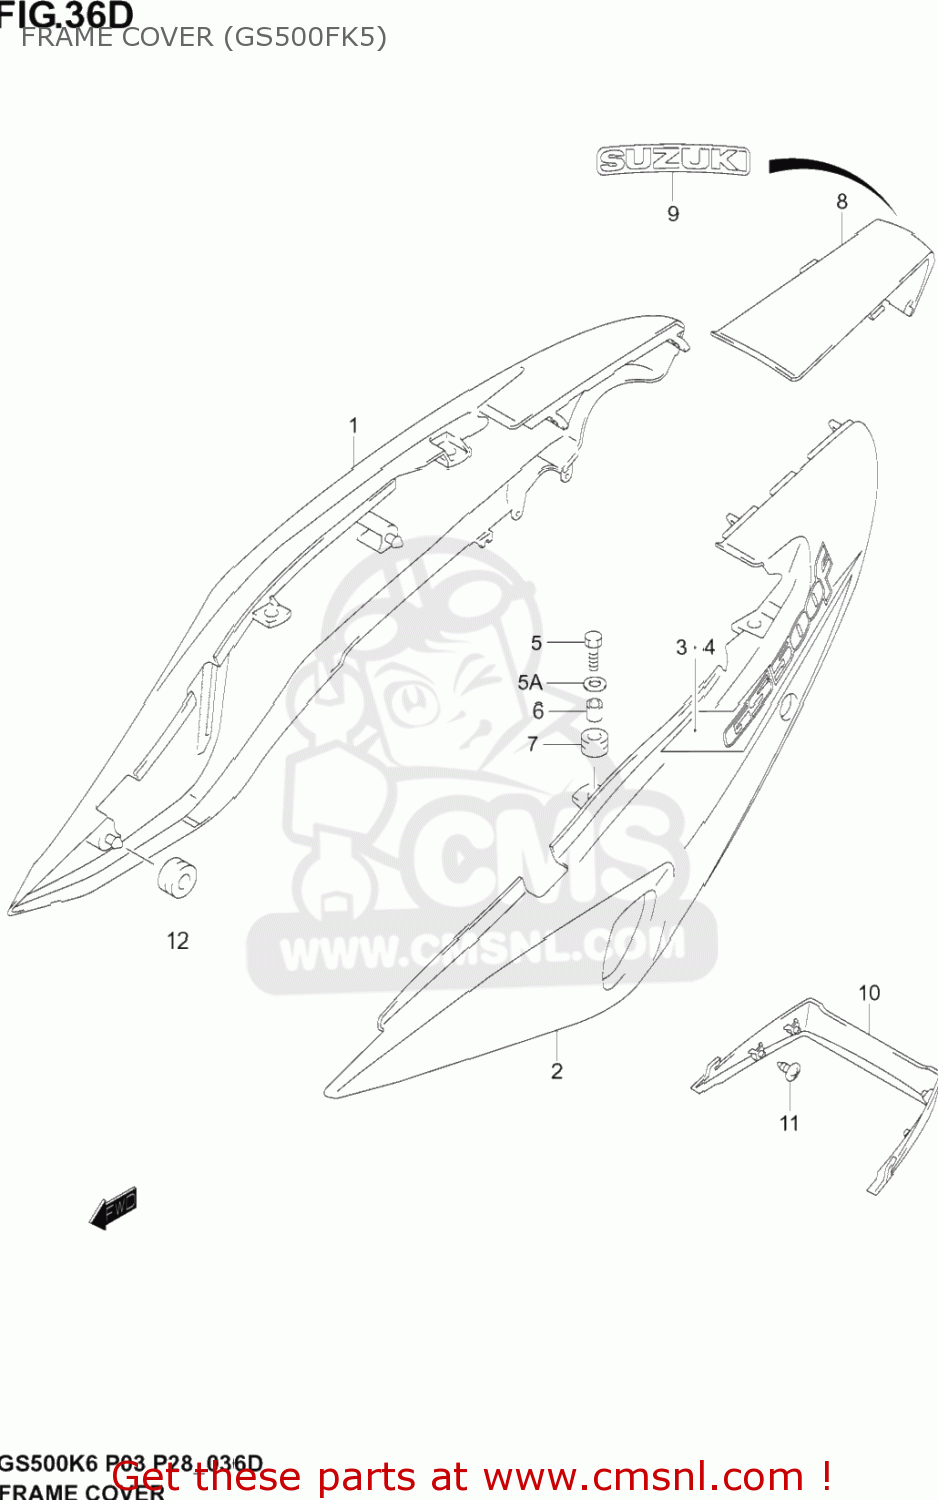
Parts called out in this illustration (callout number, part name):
1	COVER,FRAME
2	COVER, FRAME
3	TAPE RH
4	TAPE,LH
5	BOLT
5A	WASHER
6	SPACER(6.5X9X9)
7	CUSHION
8	COVER, CENTER
9	EMBLEM (SILVER
10	COVER LOWER
11	SCREW
12	CUSHION
